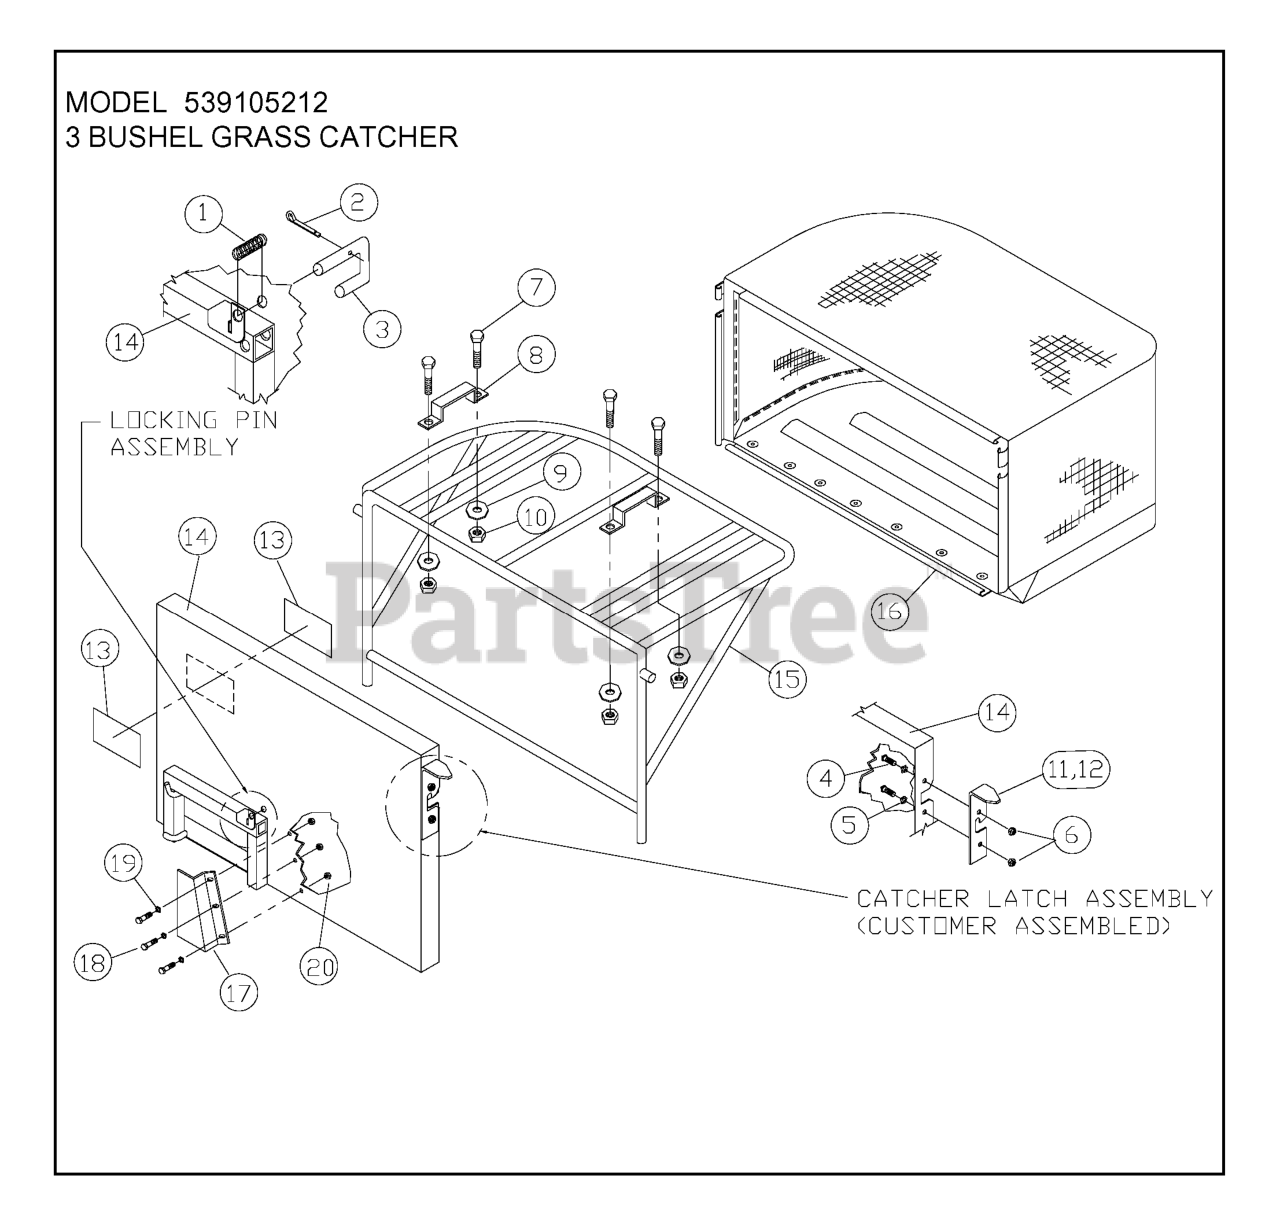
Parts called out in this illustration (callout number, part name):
1	SPRING, COMPRESSION
2	LOCKING PIN
3	COTTER PIN 3/32 X 1/2
4	SCREW #10-24 X 5/8
5	WASHER, WAVE SPRING
6	NUT 10-24 NYLOC
7	HCS 1/4C X 1
8	HOPPER HANDLE
9	WASHER 1/4 FLAT
10	NUT.1/4-20.HEX.NYLOC.ZD
11	CATCHER LATCH, RIGHT
12	CATCHER LATCH, LEFT
13	DECAL, WARNING
15	WIRE FRAME 3 BU
16	BAG, 3 BU FABRIC
17	ADAPTER SHIELD
18	HCS 5/16C X 3/4
19	WASHER 5/16 FLAT
20	NUT 5/16C CENTERLOCK
21	ADAPTER PLATE
